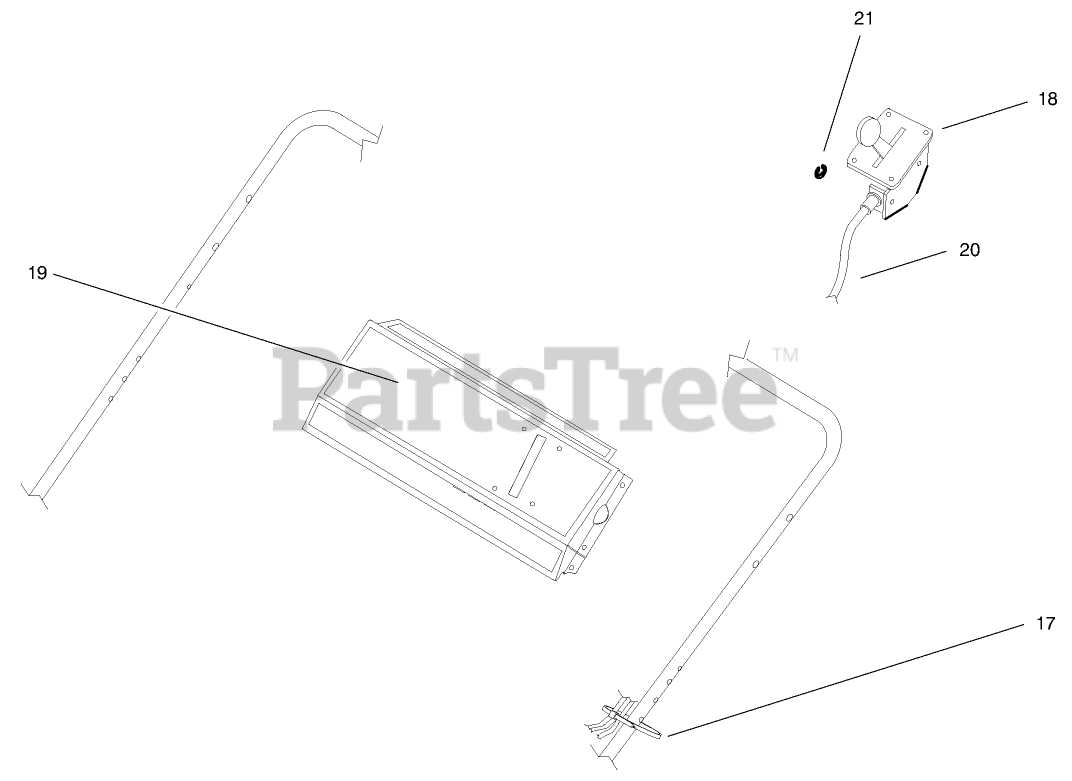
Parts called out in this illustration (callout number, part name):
17	TIE-CABLE
18	CONTROL-THROTTLE
20	CABLE-THROTTLE
21	E-RING
